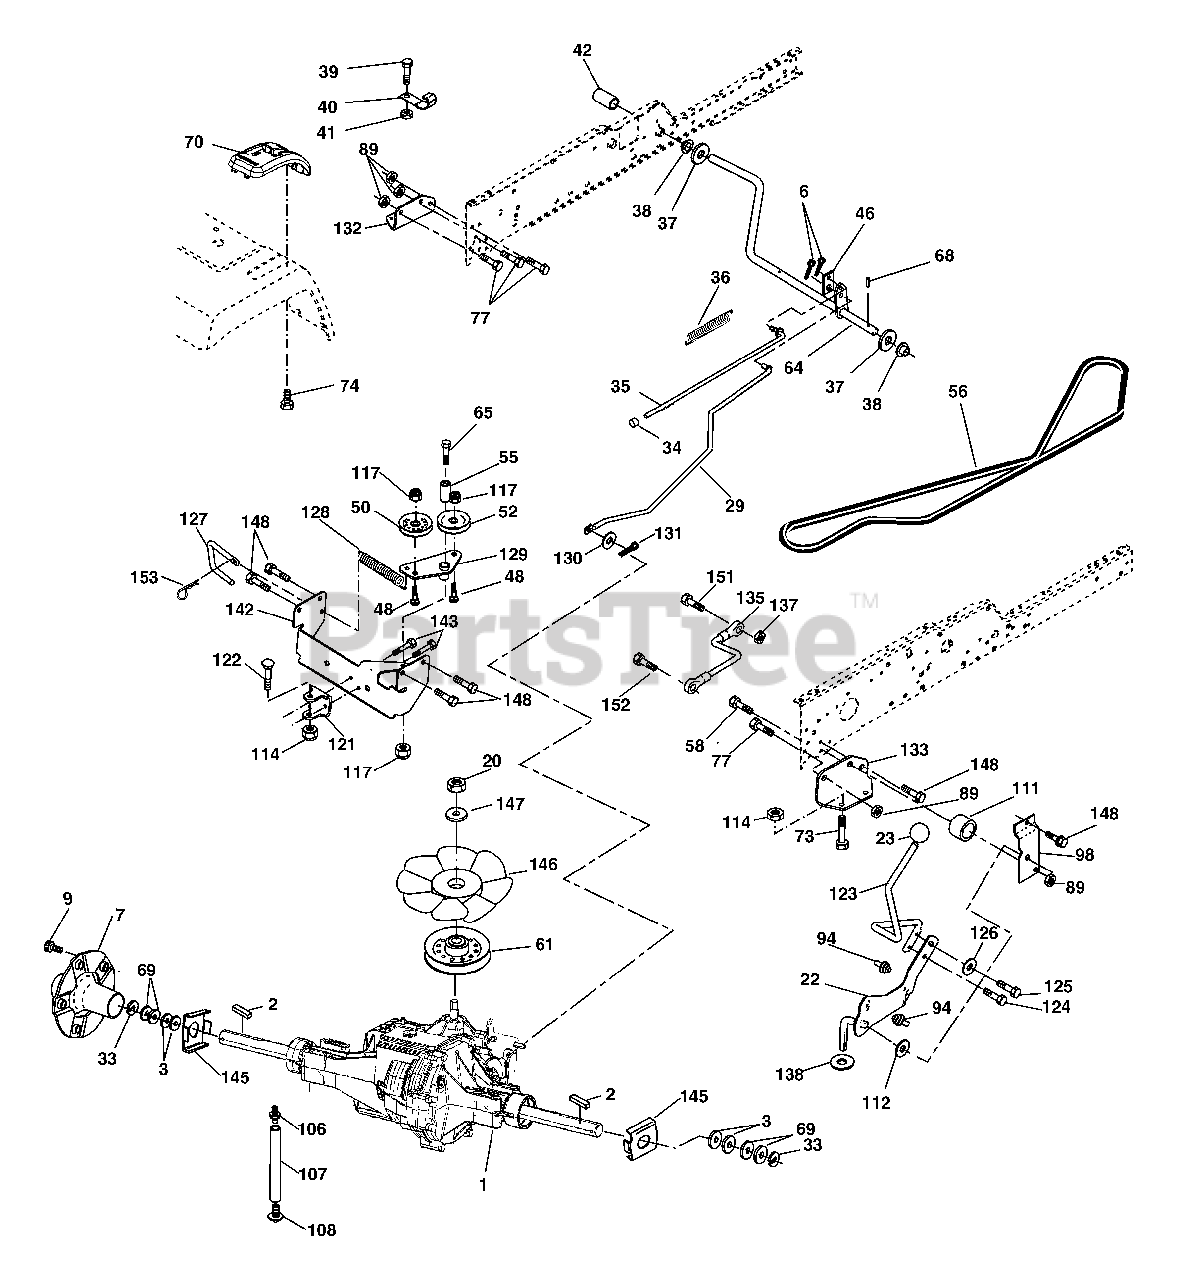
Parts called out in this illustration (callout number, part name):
2	Key Sq. 1/4 x 2.5
3	Washer Thrust
6	Pin, Cotter
7	Wheel, Hub Assembly
9	Bolt, Hub
20	Nut
22	Lever Asm Shift
23	Knob
29	Brake, Rod
33	Ring E
34	Cap, Parking Brake
35	Rod, Parking Brake
36	Spring, Drive Ground
37	Washer 25/32 x 1-1/4 x 16 Ga.
38	Nyliner
39	Screw, Fin. #10-24 x 1
40	Actuator, Interlock Switch
41	Nut Centerlock 10-24 unc
42	Cover, Pedal
46	Retainer, Spring
48	Bolt Carr. Shoulder 3/8-16 x 1-3/4 Gr. 5
50	Pulley, Idler, Flat
52	Pulley, Idler, Grooved
55	Bearing, Idler
56	V-Belt
58	Bolt Fin Hex 7/16-14 x 1-1/2
61	Pulley, Transaxle
64	Shaft, Brake Pedal
65	Bolt, Shoulder
68	Pin, Roll
69	Washer
70	Console Shift
73	Bolt Hex Flghd 5/16-18 x 3 Gr. 5
74	Screw Hex Wsh. Hi-Lo 1/4-1/2
77	Bolt Fin Hex 7/16-14 x 1
89	Nut Crownlock 7/16-14 unc
94	Fastener Christmas Tree
98	Bracket Shift
106	Cap Asm Vent Hydro Gear
107	Line Fuel Hydro 15" VGT
108	O-Ring Asm Hydro Gear
111	Spacer Shift Lever VGTH
112	Washer Nylon High Temp
114	Nut Lock Hex W/Ins 5/16-18 unc
117	Nut, Lock Flg. 3/8-16
121	Bracket Strap Torque
122	Bolt 5/16-18 x 2.50
123	Rod Shift
124	Bolt Shoulder 5/16-18 x .561
125	Screw 5/16-18 x 5/8
126	Washer Srrtd 5/16 ID x 1.0 x .125
127	Link Control Clutch
128	Spring Drive GRND
129	Bracket Asm Idler Tensioning
130	Washer 13/32 x 5/8 x 16 Ga.
131	Pin Cotter 3/32 x 3/4
132	Bracket Mtg Hydro 3500 LH VGT
133	Bracket Mtg Hydro 3500 RH VGT
135	Link Asm Control Hydro 3500
137	Nut Lock 5/16-18 NC Thd.
138	Washer Thrust 5/8 x 1.10 x 1/32
142	Strap Torque HG-3500
143	Screw 5/16-18 x 3/4
145	Washer Axle Flange HG-3000
146	Fan 7" Hydro
147	Washer
148	Screw 3/8-16 x .75
151	Bolt Fin Hex 5/16-18 x 7/8
152	Bolt Hex 5/16-18 x 1
153	Spring Retainer
